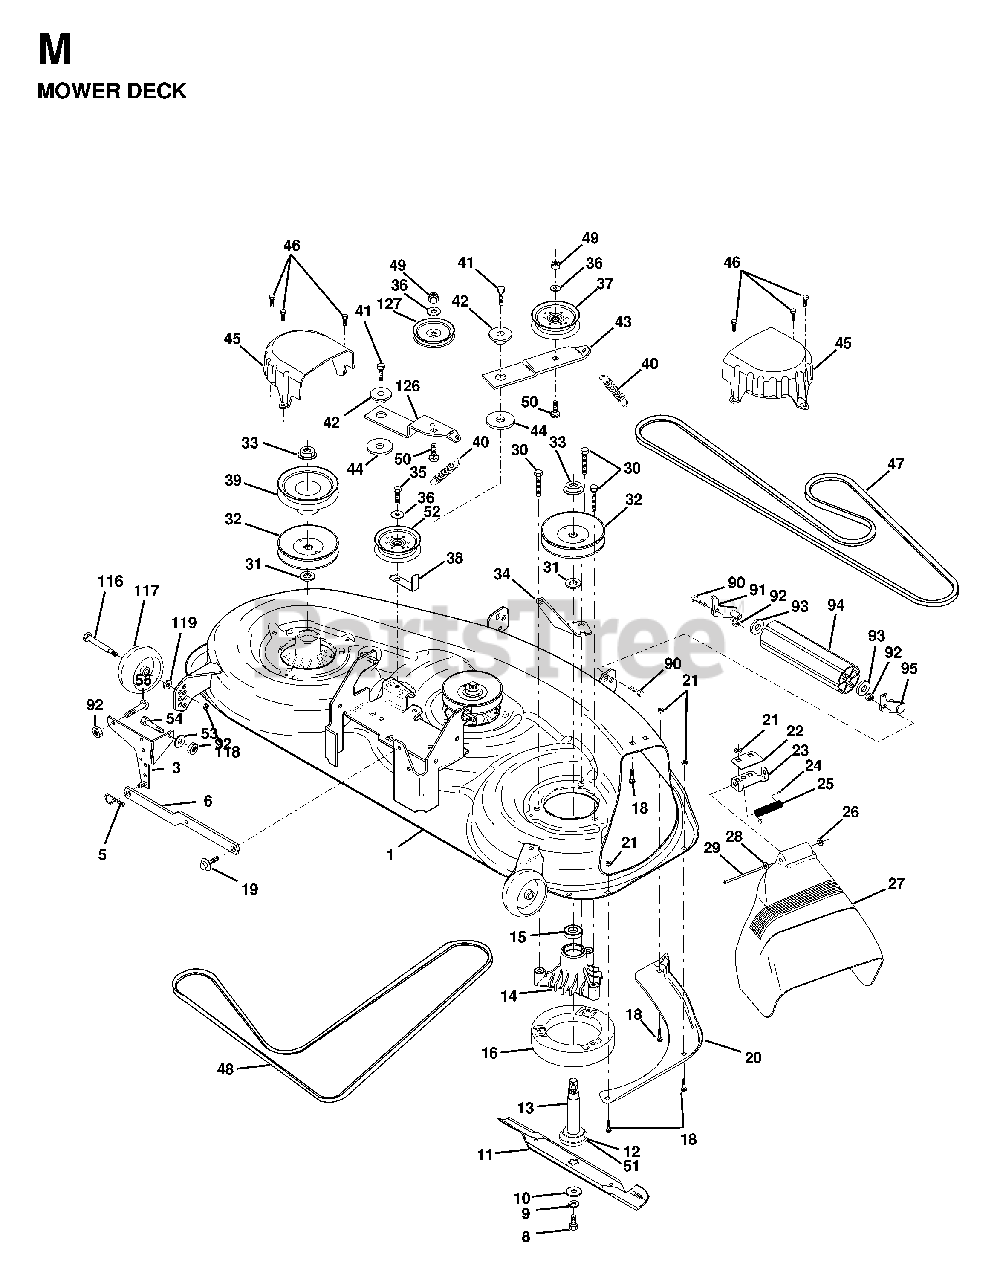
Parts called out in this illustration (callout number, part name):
1	HOUSING MOWER
3	BRACKET SWAY BAR
5	RETAINER-SPRNG RB
6	REAR SUSP ARM
8	BLADE BOLT
9	LOCKWASHER
10	WASHER.BLADE
11	BLADE 46"
12	BEARING
13	SHAFT.ASM.W/BEARING
14	HOUSING.MANDREL
16	STRIPPER
18	BOLT
19	BOLT SHD 5/16-18
20	BAFFLE, VORTEX MOWER 46"
21	LOCKNUT
22	STIFFENER BRACKET
23	DEFLECTOR BRACKET
24	CAP-SLEEVE LT
25	SPRING TORSION
26	NUT PUSH M
27	SHIELD, DEFLECTOR MOWER
28	WASHER
29	ROD.HINGE
30	SCREW
31	WASHER
32	PULLEY, MANDREL
33	NUT
34	ANCHOR, SPRING DECK 46"
35	SCREW LT
37	FLAT IDLER PULLEY
38	KEEPER
39	PULLEY.DRIVEN.DECK.46"
40	SPRING.SEC.44"VEN
41	SCREW
42	SPACER RETAINER
43	ARM IDLER DECK 46"
44	HARDENED WASHER
45	COVER MANDREL 46
46	SCREW.1/4-20X5/8
47	BELT V SECONDARY
48	V-BELT PRIMARY 50"
49	LOCKNUT
50	BOLT.3/8-16X1.50
51	WASHER FELT
52	PULLEY IDLER FLAT 46 PRI DRIVE
53	WASHER
55	BOLT D
90	BOLT
91	BRACKET LH (A)
92	NUT
94	NOSE ROLLER
95	BRACKET RH (B)
118	LOCKNUT
119	WASHER
126	ARM IDLER PRIM 46
127	PULLEY.IDLER.4.25
